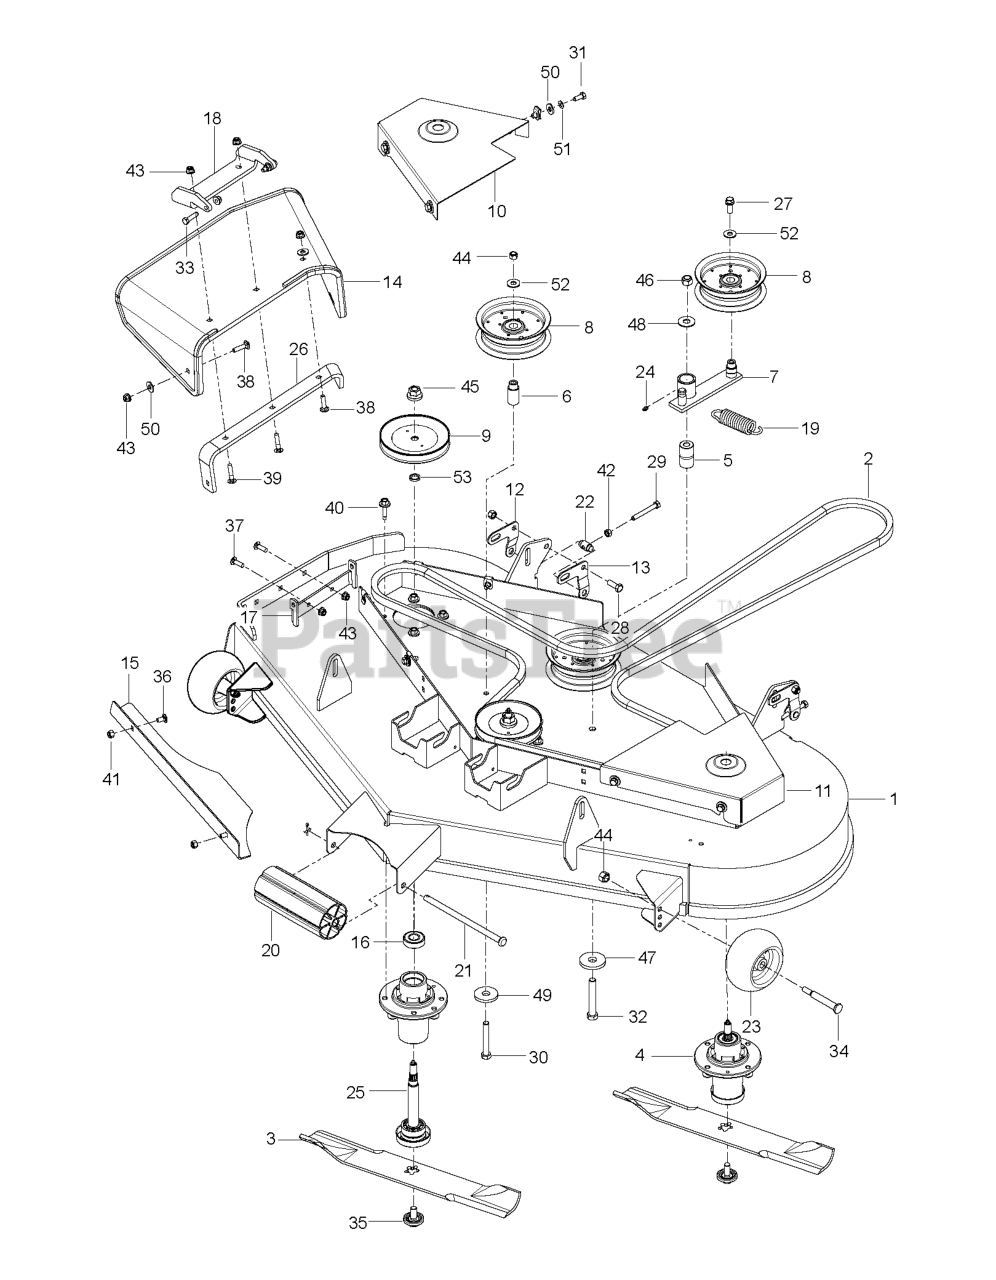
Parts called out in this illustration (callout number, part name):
1	DECK.SVC.52'W/DCLS.REDMAX.672
2	BELT, B, 148.5
3	BLADE, 18"
4	MANDREL ASM, CAST IRON
5	PIVOT BUSHING
6	IDLER BUSHING
7	IDLER ARM
8	PULLEY, IDLER
9	PULLEY MANDREL
10	SHIELD BELT RH 52" SNAPPER RED
11	SHIELD BELT LH 52" SNAPPER RED
12	BRACKET.RT.PNT.MS431
13	BRACKET.LH.PNT.MS431
14	CHUTE, RUBBER DISCHARGE 52/61"
15	CONFINEMENT PLATE, 52"
17	BRACKET MZT CHUTE SNAPPER RED
18	PIVOT BRACKET - CHUTE
20	NOSE ROLLER 48"
21	ROD.ROLLER.NOSE.NARROW.48"
22	TRUNION, PITCH
23	WHEEL GAGE DONUT
24	ZERK
25	SHAFT ASM MANDREL
26	BRKT, REINF - CHUTE 52/61"
27	4CS 3/8C X 1 SERRATED HEAD
29	HCS 5/16-18 X 2 1/2 TPBLT
30	BOLT.HEX.FIN.3/8-16 X 3.GR5
31	HCS 5/16C X 1
32	HCS 1/2-13 X 3-1/4 GD 5 ZD
33	BOLT.5/16-18X1-1/4 FULL.THREAD
34	BOLT, SHOULDER
35	BOLT.WASHER.ASM.7/16-2
36	BOLT
37	RHSSNB 5/16C X 1.0
38	BOLT, CARRIAGE 5/16X1-1/4
39	RHSNB 5/16-18 X 1-1/2 GR 5 ZD
40	BOLT.HEX.WASHR.HED.313-18X1.19
41	NUT.71038.31-18.HEX.NYLOCK
43	5/16-18 NYLOC FLANGE NUT
44	NUT 3/8-16 NYLOC
45	NUT.FLANGE.LOCK.TOP
46	NUT.LK.W/WSH.1/2.
47	WASHER, SUPPORT
48	WASHER.9/16 X 1 3/8 X 12 GA.
49	SPINDLE WASHER
50	WASHER
51	WASHER 5/16 LOCK
52	WASHER 3/8 FLAT
53	WASHER.SPACER.MANDREL
